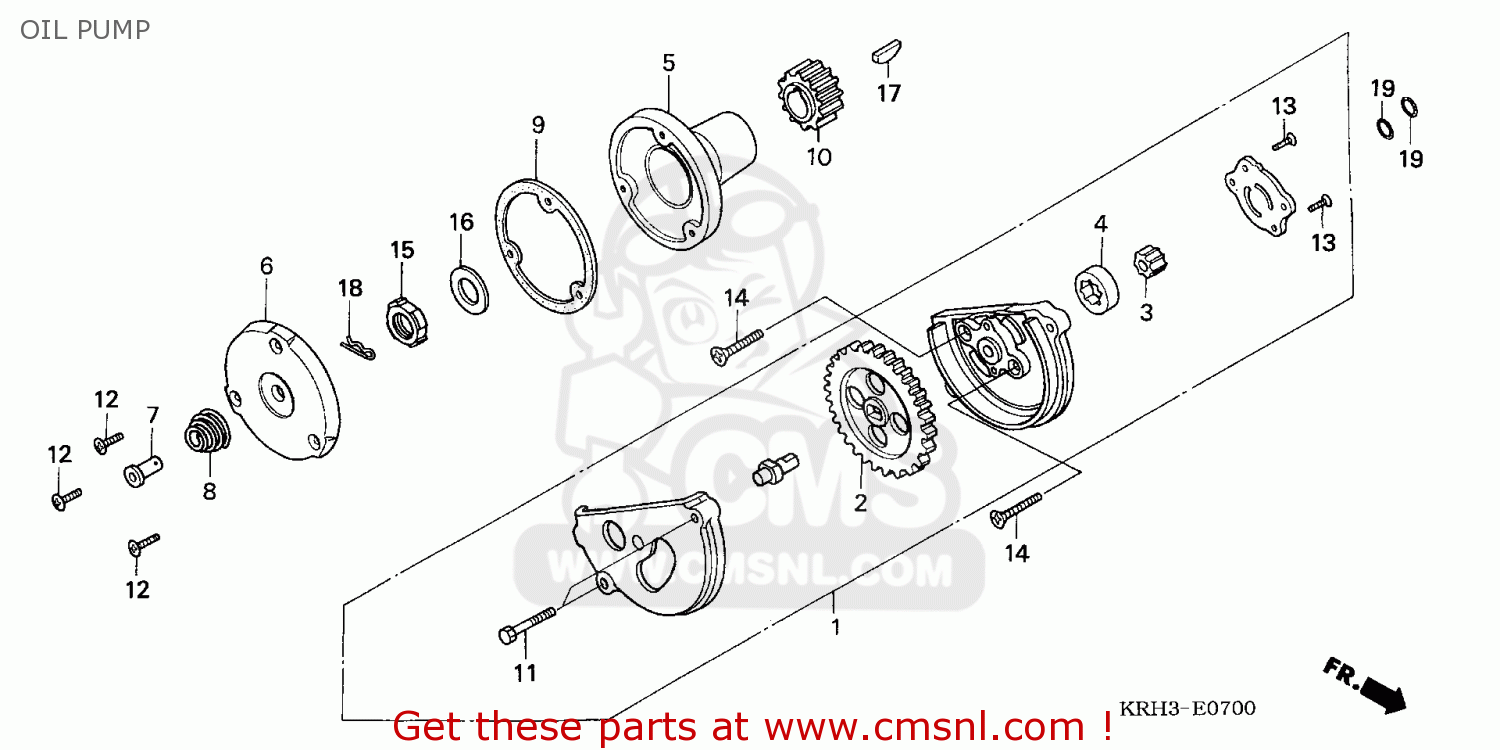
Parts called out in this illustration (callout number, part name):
1	OIL PUMP ASSY.
2	GEAR,OIL PUMP DRI
3	INNER ROTOR,OIL P
4	OUTER ROTOR,OIL P
5	ROTOR COMP,OIL FI
6	CAP OIL FILTER RO
7	OIL THROUGH
8	SPRING,OIL THROUG
9	GASKET,OIL FILTER (NAS)
10	GEAR A,PRIMARY DR
11	BOLT,HEX,5X20
12	SCREW,OVAL,5X12
13	SCREW,FLAT 4X12
14	SCREW,FLAT,6X30
15	NUT LOCK,16MM
16	WASHER,16MM
17	KEY,WOODRUFF,25X1
18	PIN,LOCK,8MM
19	O RING 9.4X2.4
